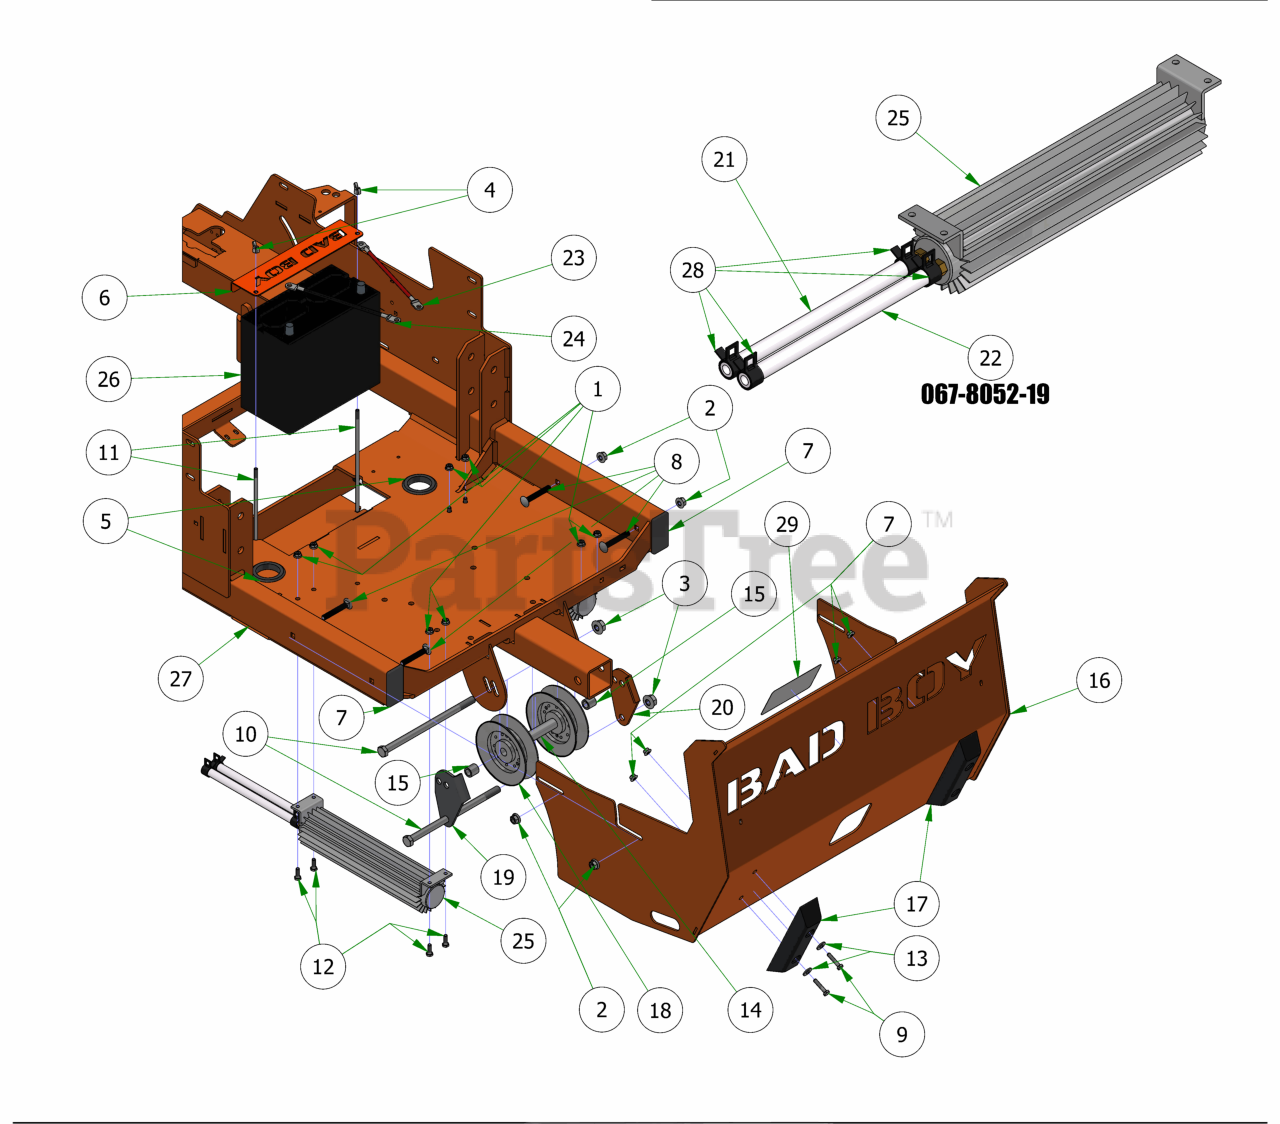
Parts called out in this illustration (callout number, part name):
1	1/4-20 NYL INSERT FLANGE LOCKNUT ZINC
2	3/8-16 NYLON INSERT FLANGE LOCKNUT (GR.F) ZINC
3	1/2-13 NYLON INSERT FLANGE LOCKNUT ZINC
4	1/4-20 WING NUT FORGED (TYPE A) LIGHT SERIES ZINC
5	2019 2" x .25 Rubber Grommet
6	2019 Horizontal Battery Hold Down Cover
7	1 1/2 x 3 Frame Plug
8	3/8" x 2 1/2" Carriage Bolt
9	1/4-20 X 1-1/4 HEX CAP SCREW (GR.5) ZINC
10	1/2-13 X 9 HEX CAP SCREW (GR.5) ZINC
11	1/4-20 X 9 CARRIAGE BOLT ZINC
12	1/4-20 X 3/4 HEX CAP SCREW (GR.5) ZINC
13	1/4 USS FLAT WASHER (3/4 OD) ZINC
14	2019 Pulley Spacer .75 x .5 x 4.375
15	.51 ID X .75 OD X .75 LGTH SOLID SPACER ZINC
16	2019 Horizontal Suspension Rear Cover
17	8" Rubber Bumper
18	2019 Outlaw Horizontal Rear V Pulley
19	Renegade Deck Belt Rear Keeper - Left
20	Renegade Deck Belt Rear Keeper-Right
21	3/8" Clear Hose - 14"
22	3/8" Clear Hose - 24"
23	Red Battery Cable - Diesel
24	Black Battery Cable - Diesel
25	2019 12" Oil Cooler With Fittings
26	Battery - Diesel/Renegade Models PF-516
27	2019 Renegade Gas Frame - Powdercoated
28	3/8" Hose Clamp
29	2019 Renegade Pump Belt Route Decal
